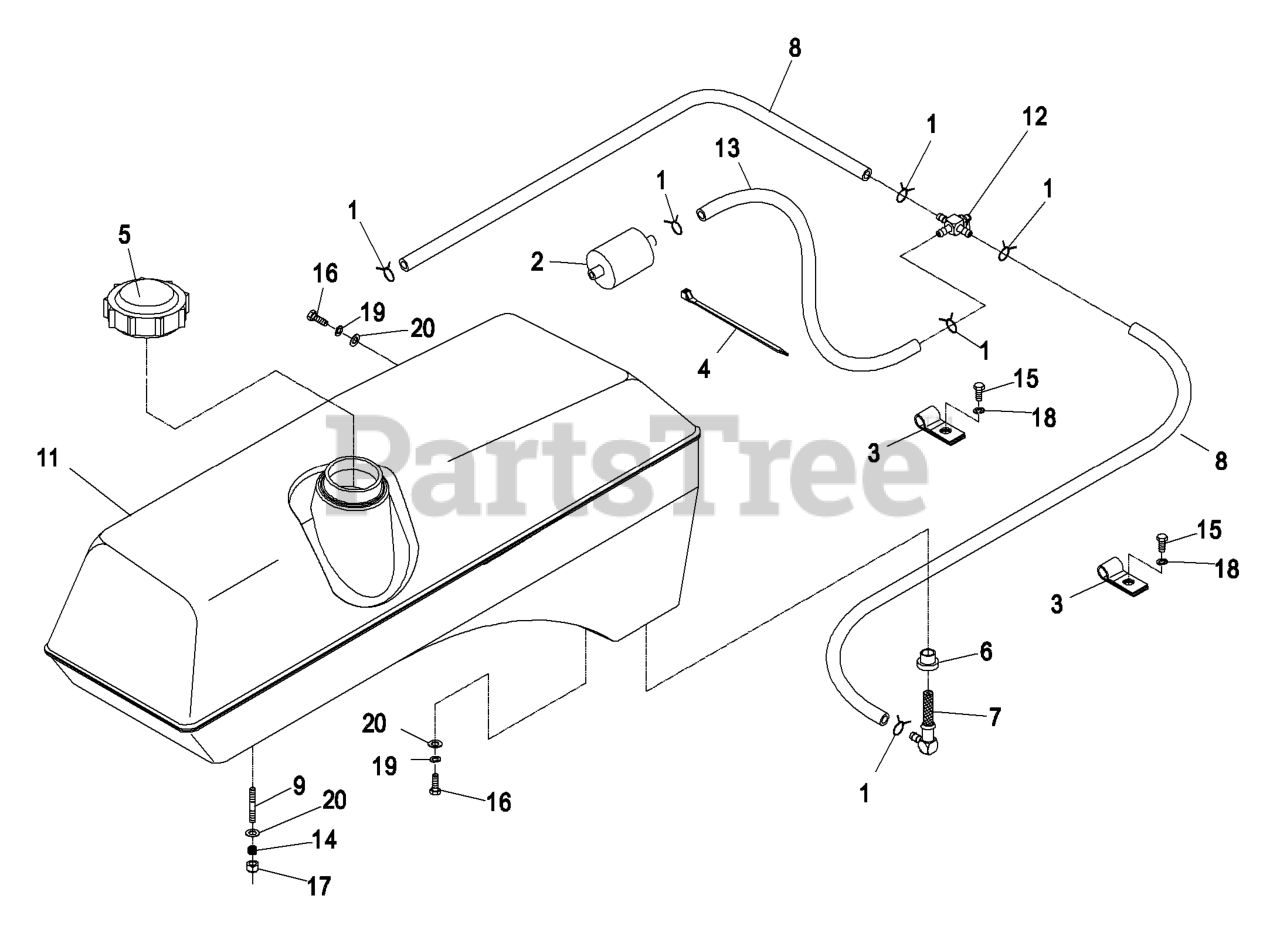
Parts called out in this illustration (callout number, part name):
2	Fuel Filter
3	CLIP-LOOM
4	TIE-PLASTIC
7	ELBOW-TANK, FUEL
8	HOSE-FUEL
9	STUD
12	VALVE-FUEL
14	SPRING-TANK, FUEL
15	SCREW-HH
16	SCREW-HH
17	NUT-LOCK, NI
18	WASHER-LOCK
19	WASHER-LOCK
20	WASHER-PLAIN
